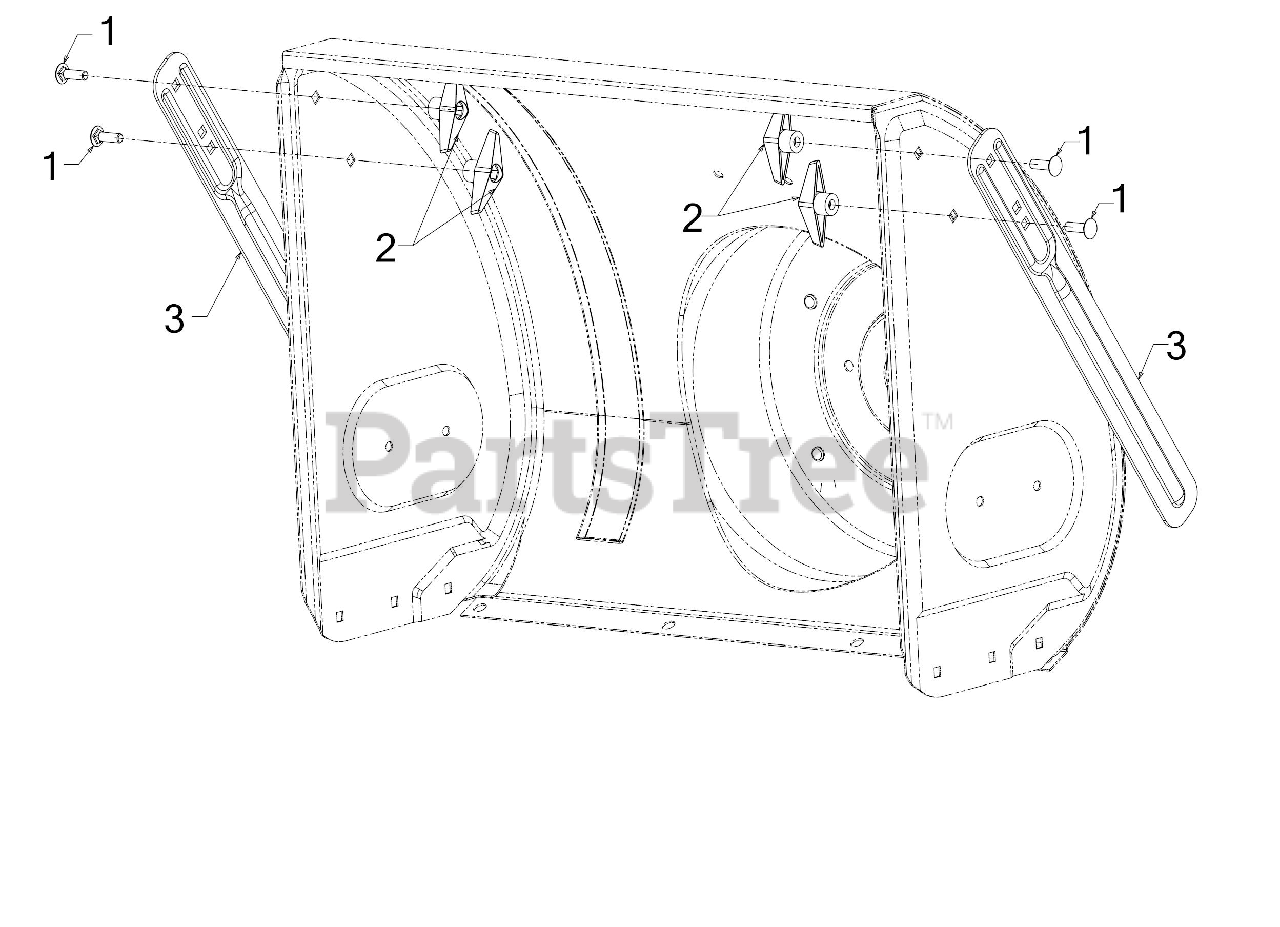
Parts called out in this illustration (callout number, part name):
1	CARRIAGE BOLT 5/16-18 x 1.00
2	WING NUT KNOB
3	BLADE-GUIDE (DRIFT
